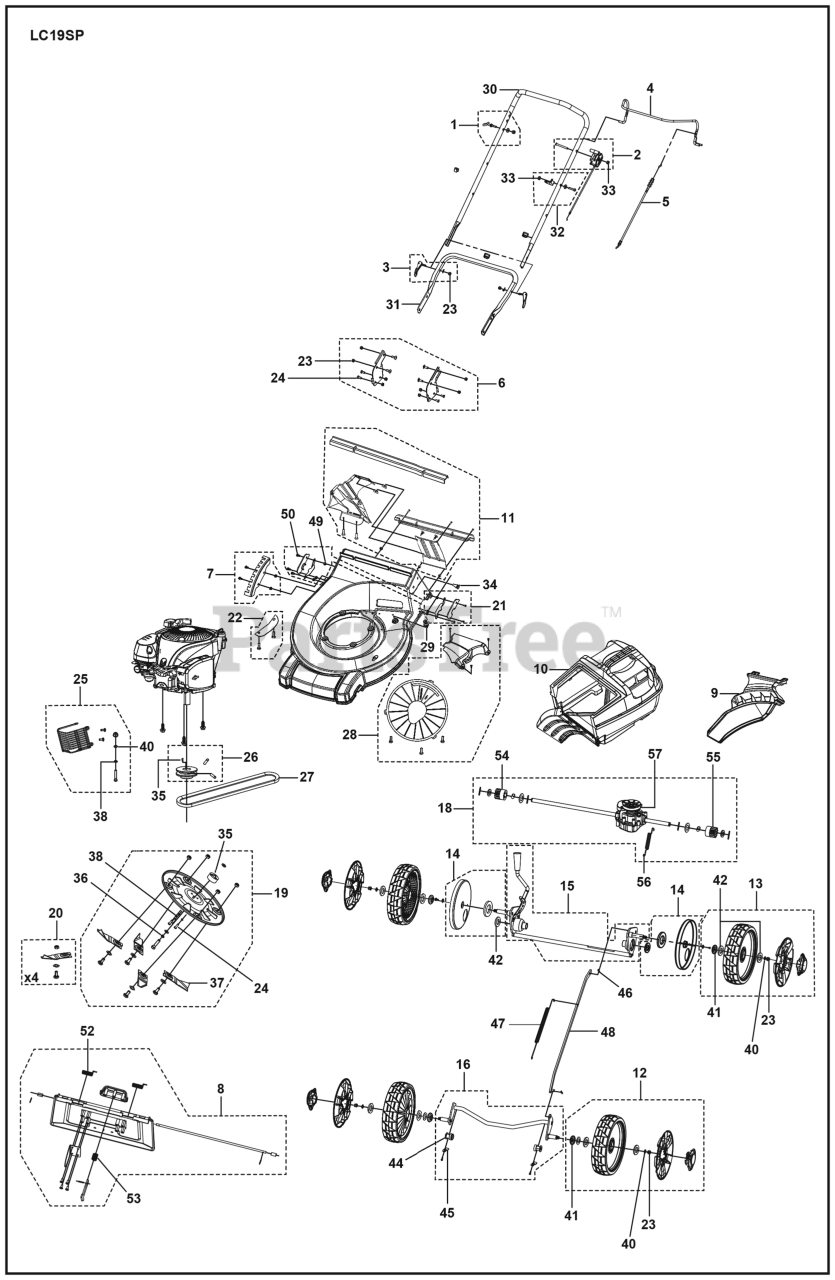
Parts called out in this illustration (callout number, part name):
23	LOCKNUT M8
33	LOCKNUT M6
36	Spring Washer
38	WASHER SPRING LOCK WASHER WITH
49	LOCKNUT M5
50	SCREW M6SF 5X16
